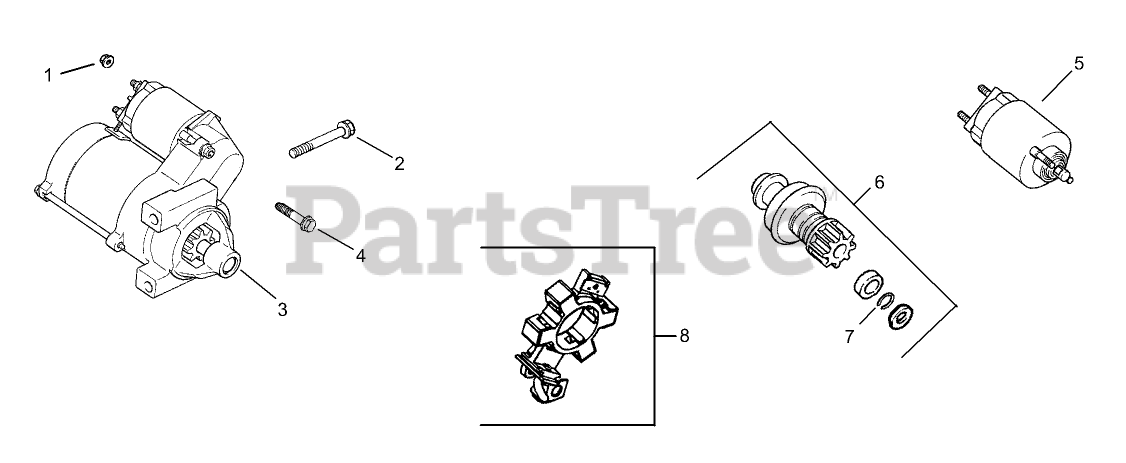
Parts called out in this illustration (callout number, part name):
1	NUT-FLANGE (M8X1.25)
2	SCREW-FLG (M8X1.25X80)
3	Starter, solenoid shift assembly (Includes 4-8)
4	SCREW-TORX HEAD, EXTERNAL
5	Kit, solenoid (Includes 4)
6	Kit, pinion drive (Includes 7)
7	RING-RETAINING
8	BRUSH HOLDER KIT
